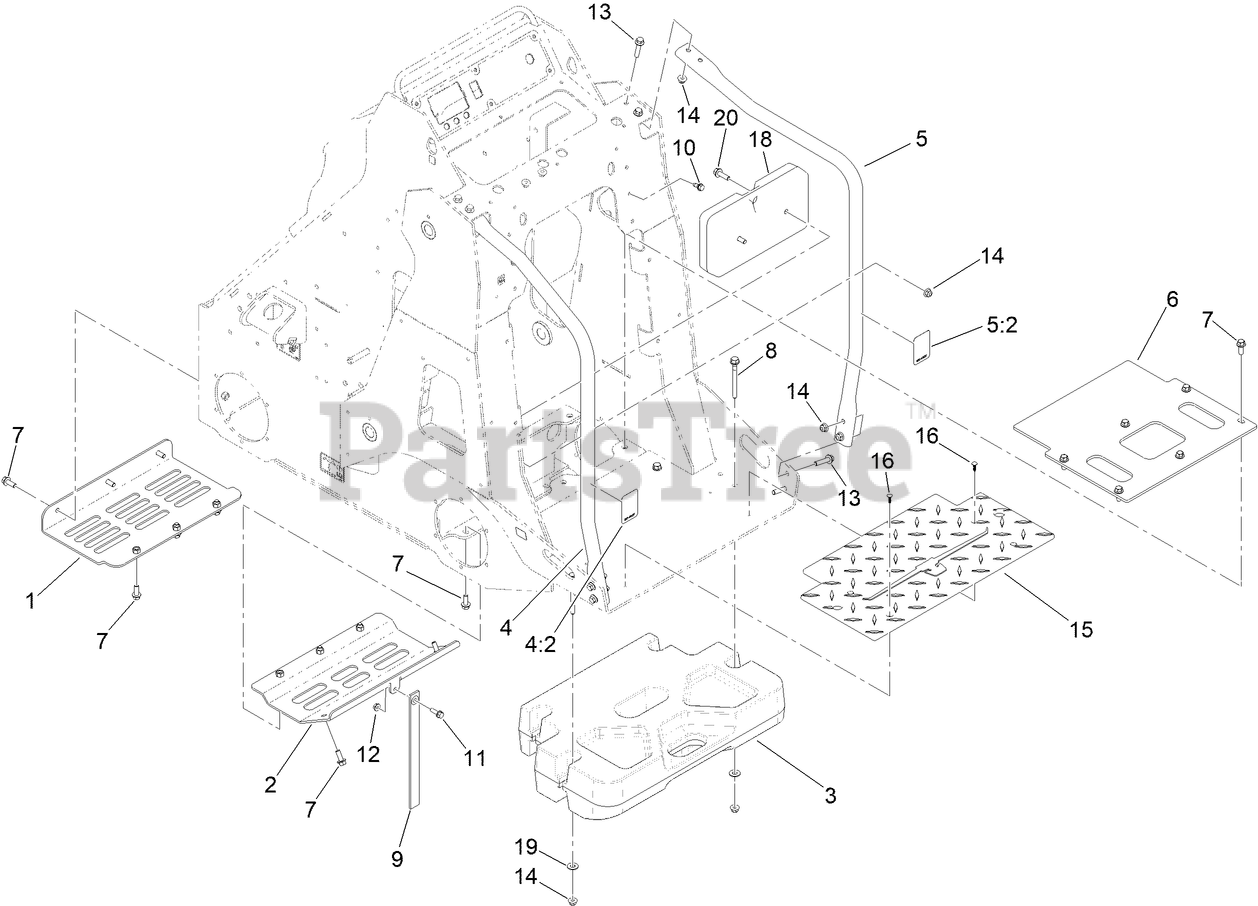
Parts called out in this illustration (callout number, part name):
1	SKID PLATE ASM, FRONT
2	SKID PLATE ASM, REAR
3	COUNTERWEIGHT
4	TUBE-HANDLE,LH
4:2	REFLECTOR
5	TUBE-HANDLE,RH
5:2	REFLECTOR
6	PLATE-COVER,MOTOR
7	SCREW-HHF
8	SCREW-HHF 5/8, PATCH
9	STRAP, STATIC
10	SCREW-SHOULDER
11	SCREW-HHF
12	NUT-FLANGE
13	SCREW-HHF
14	NUT-HF, NI
15	PAD - FOOT
16	PLUG-PLASTIC
18	COUNTERWEIGHT
19	WASHER-FLAT
20	SCREW-HHF
